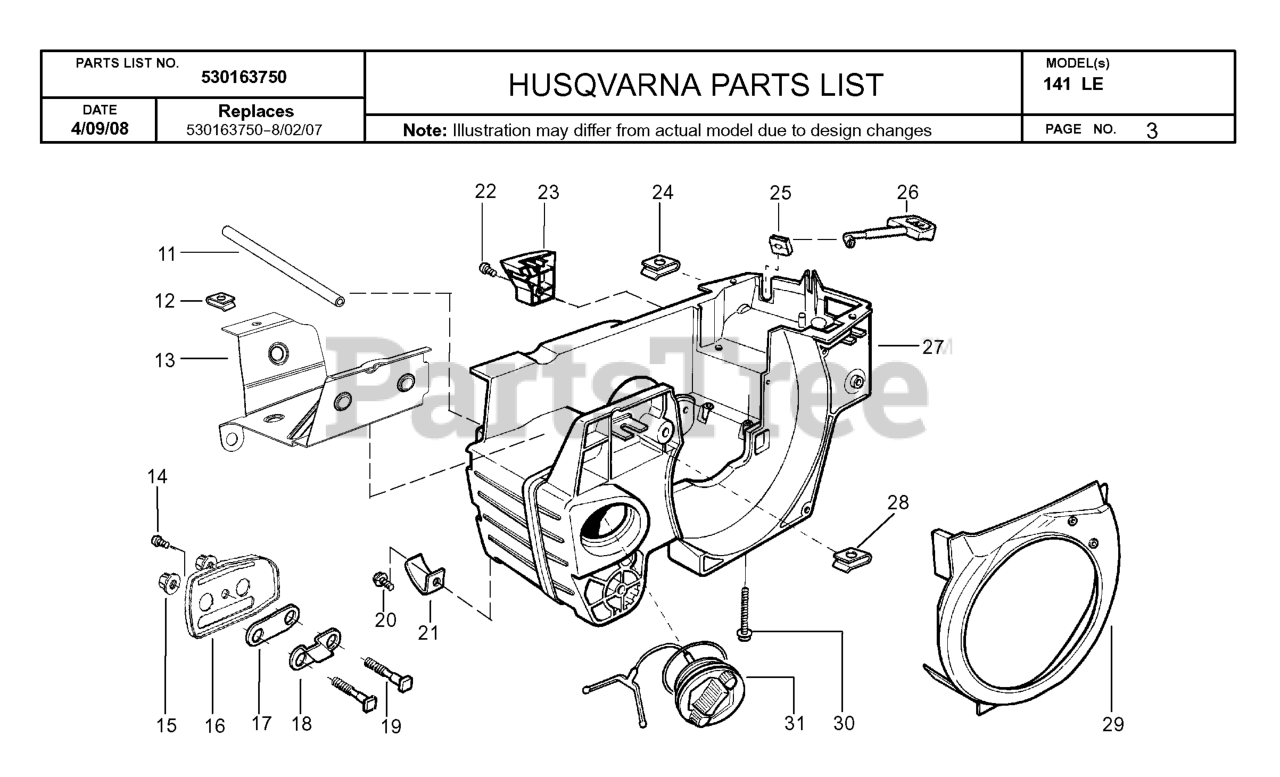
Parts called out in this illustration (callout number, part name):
1	CLUTCH ASSEMBLY
2	FRICTION DISC,CLUTCH 36/41
3	CLUTCH DRUM ASSY
4	THRUST WASHER
5	OIL PICKUP
6	SCREEN/FILTER
9	OILER ASS'Y 36/41
10	OILER GEAR 36/41
13	HEATSHIELD, LOWER
17	OIL TANK GASKET
18	PLATE,BAR MOUNT
19	BAR BOLT 36/41
21	CHAIN CATCHER 36/41
23	LIMITER COVER
25	CHOKE GUIDE 36/41
26	CHOKE 36/41
27	CRANKCASE ASSY
29	AIR CONDUCTOR 36/41
30	SCREW M5-0.8X35M TAP
